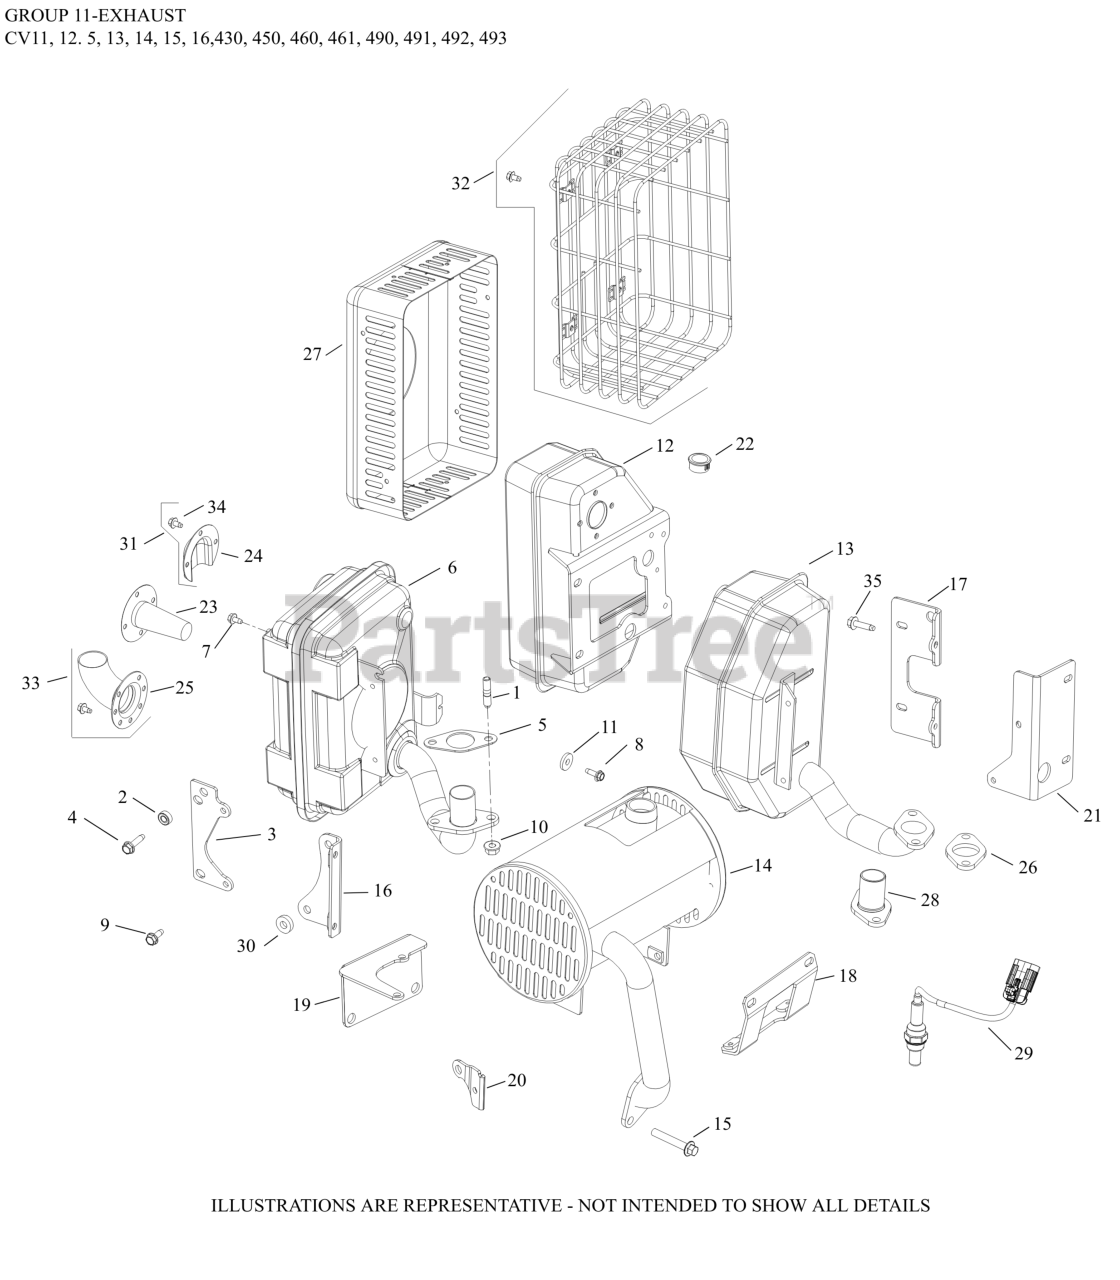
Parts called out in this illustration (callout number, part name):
5	GASKET, EXHAUST MANIFOLD
9	SCREW,FLG THD FRM M6X1.0X16-(#25086397S)
20	BRACKET, LIFTING STRAP-(#DSC)
